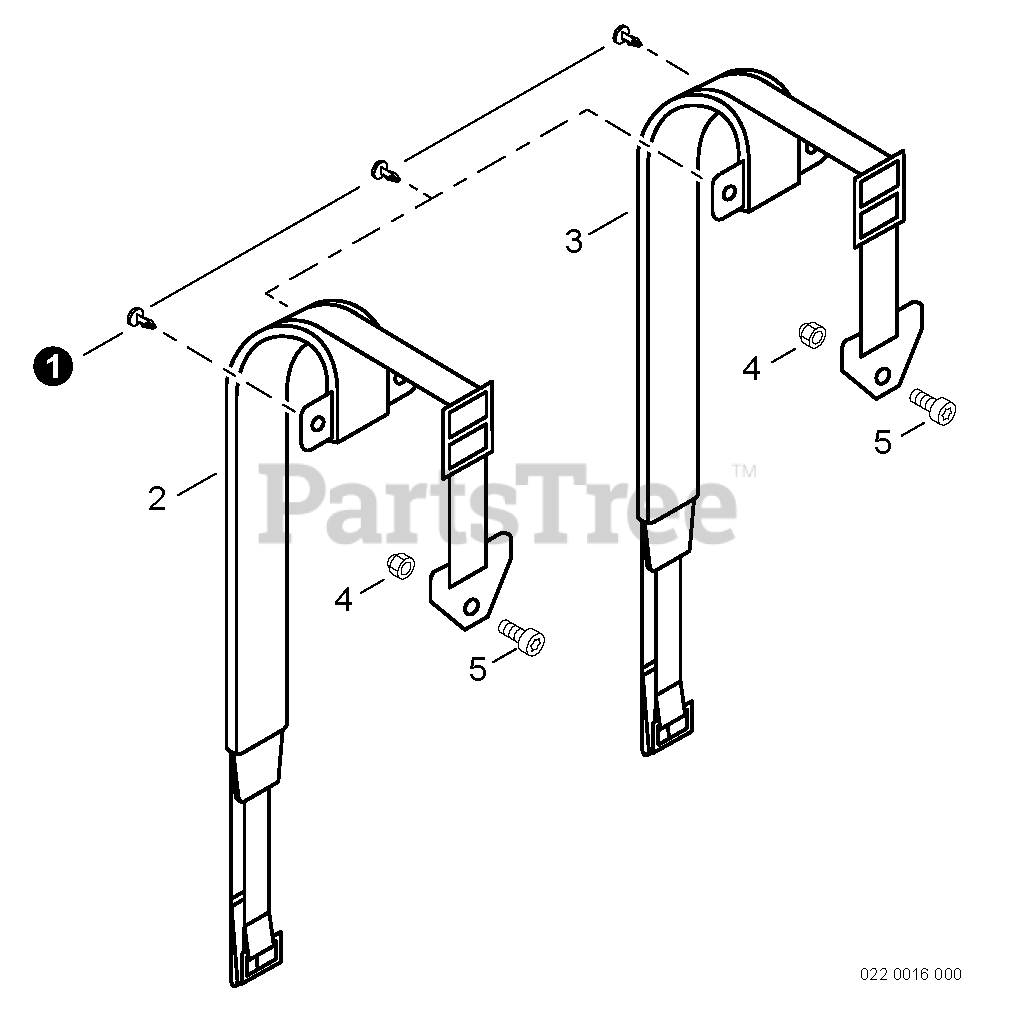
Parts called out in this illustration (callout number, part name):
2	HARNESS ASSY, LEFT
3	HARNESS ASSY, RIGHT
4	NUT, LOCK M5
5	BOLT, TORX 5×30
